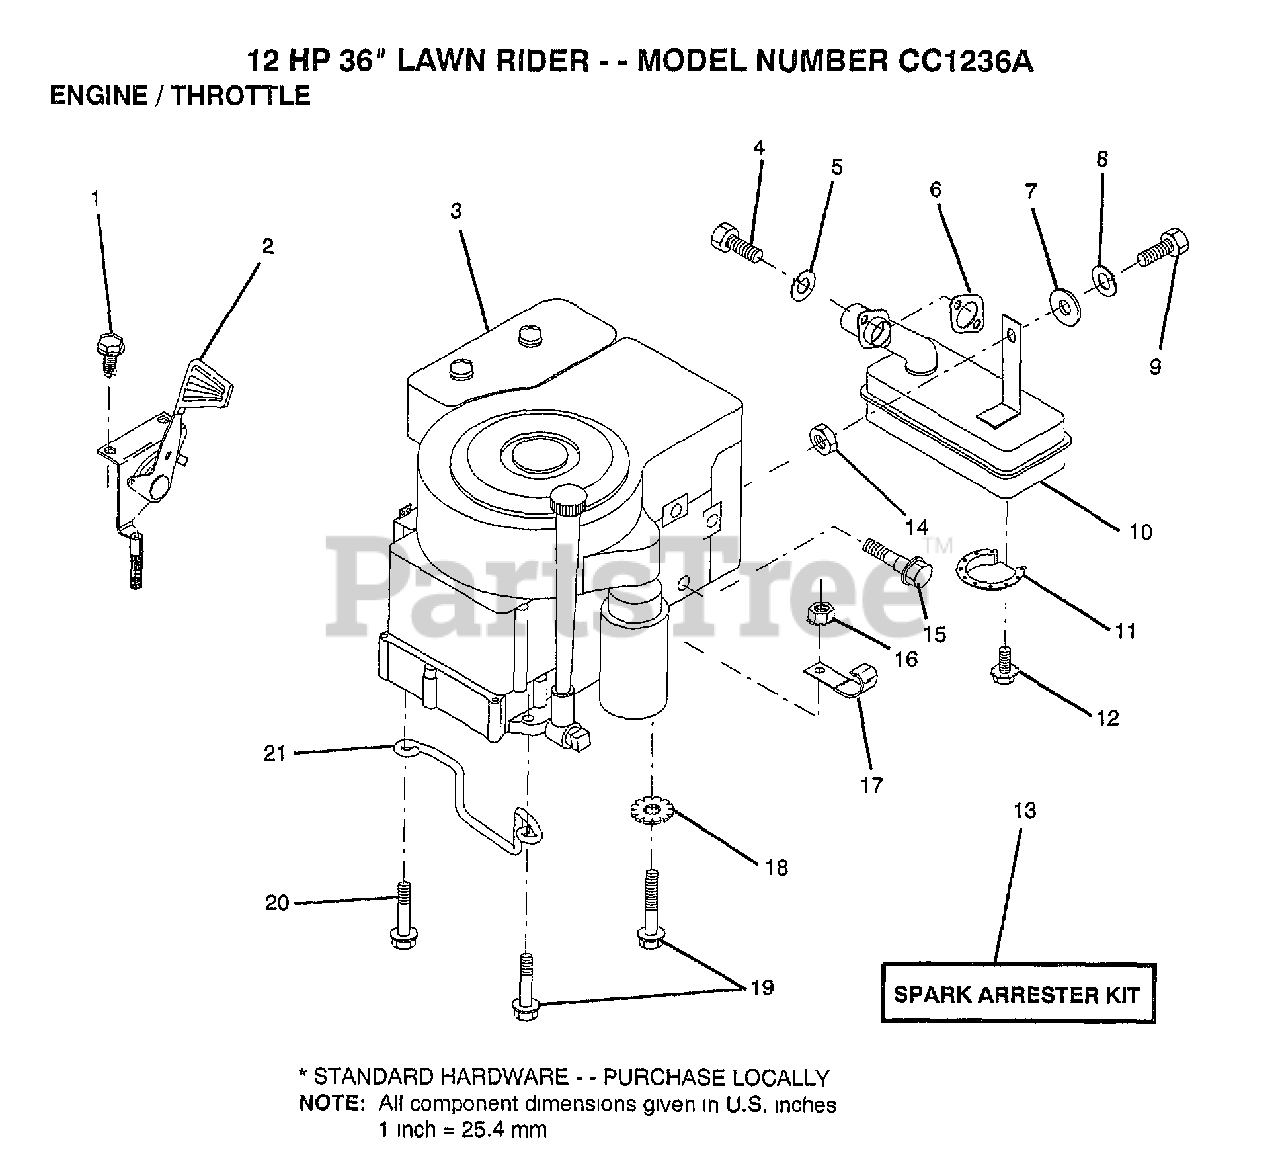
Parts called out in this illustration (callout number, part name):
1	SCREW
3	ENGINE BRIGGS AND STRATTON
4	SCREW
5	LOCKWASHER
8	LOCKWASHER
10	MUFFLER
11	DEFLECTOR.222573
14	NUT.HEX.5/16-18
15	BOLT T
16	NUT
17	CLIP T
18	LOCKWASHER
19	SCREW LT
20	SCREW LT
21	"KEEPER,DR BELT GR"
